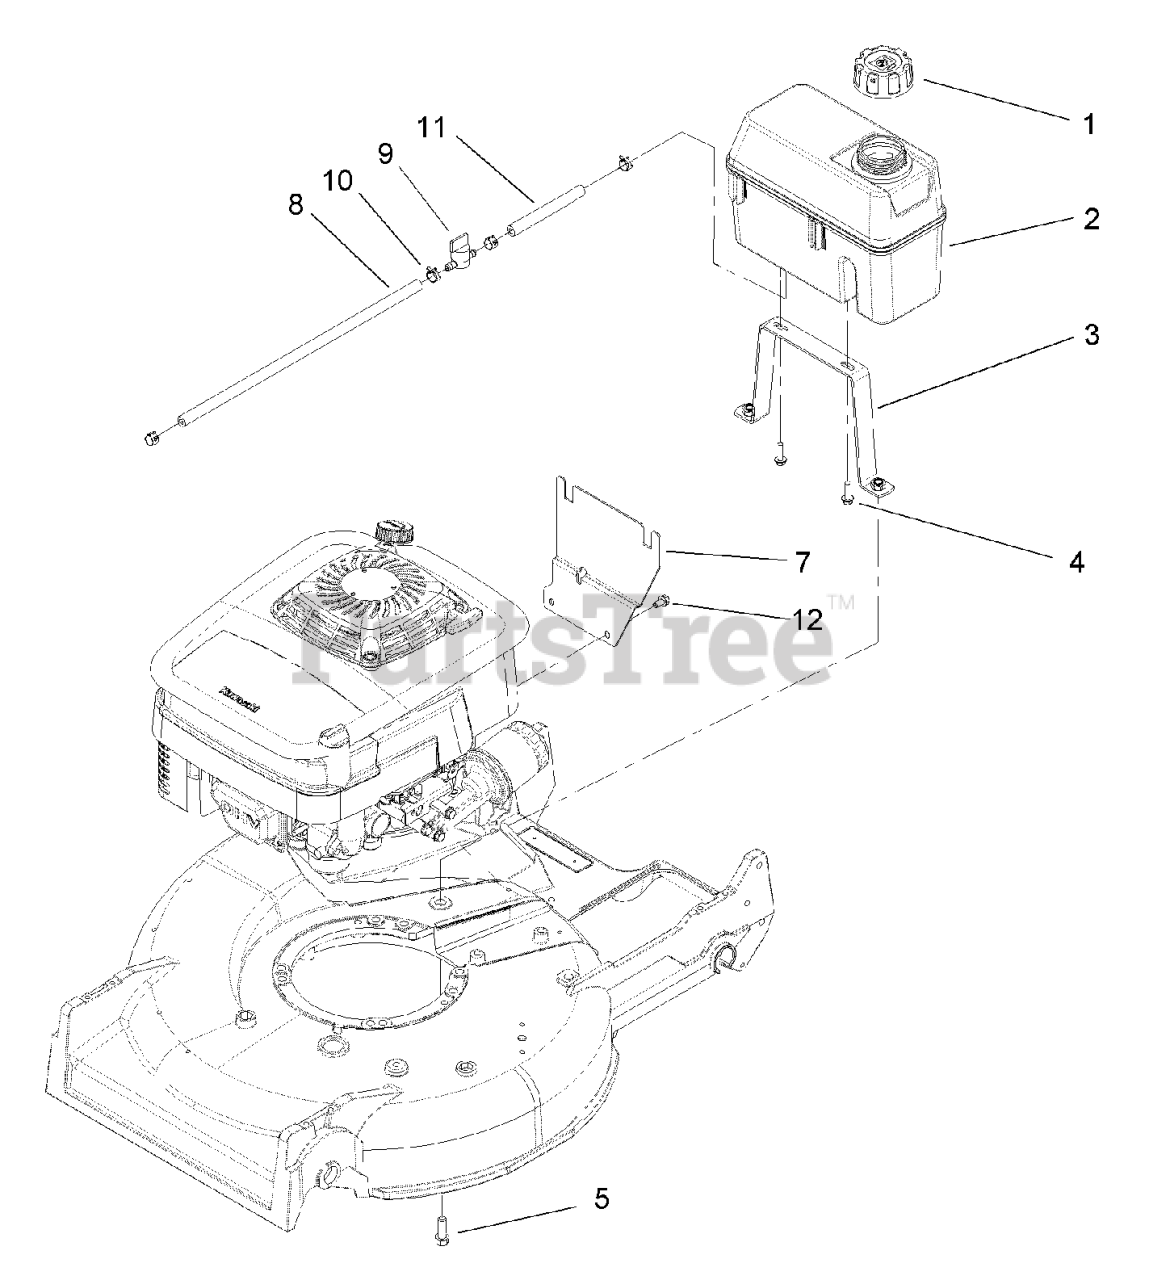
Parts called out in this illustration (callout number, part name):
1	CAP-GAS
4	SCREW-HWH
5	SCREW-TAPTITE
7	BRACKET-TANK
9	VALVE-FUEL
10	CLAMP-HOSE
12	SCREW-HWH
